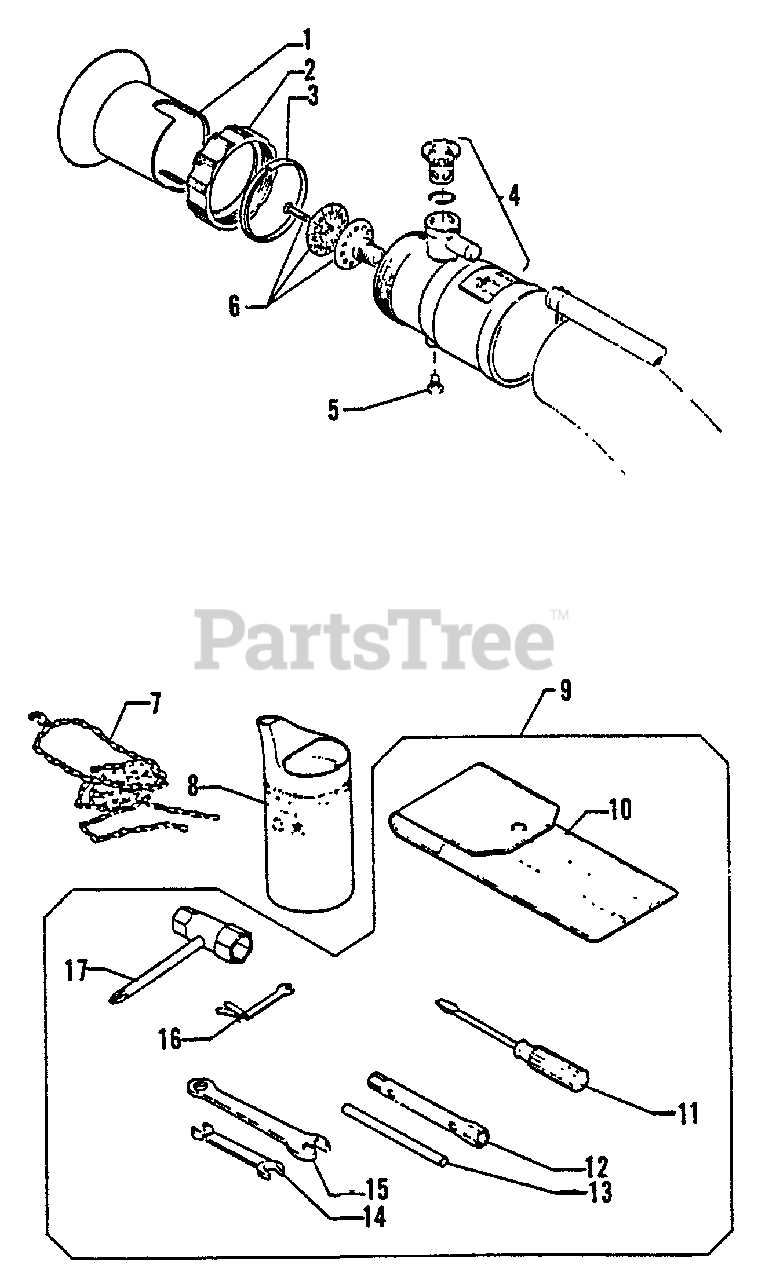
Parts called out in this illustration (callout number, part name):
4	CONTROL, VOLUME
5	SCREW - 5X12
7	CHAIN
8	MIXER, FUEL
9	TOOL KIT
10	BAG, TOOL
11	SCREWDRIVER - (-)
12	SOCKET WRENCH - 8X10mm
13	ROD, HANDLE
14	SPANNER - 8X10mm
15	SPANNER - 10X21mm
16	Magneto spanner
17	BOX SPANNER 14 X 21
